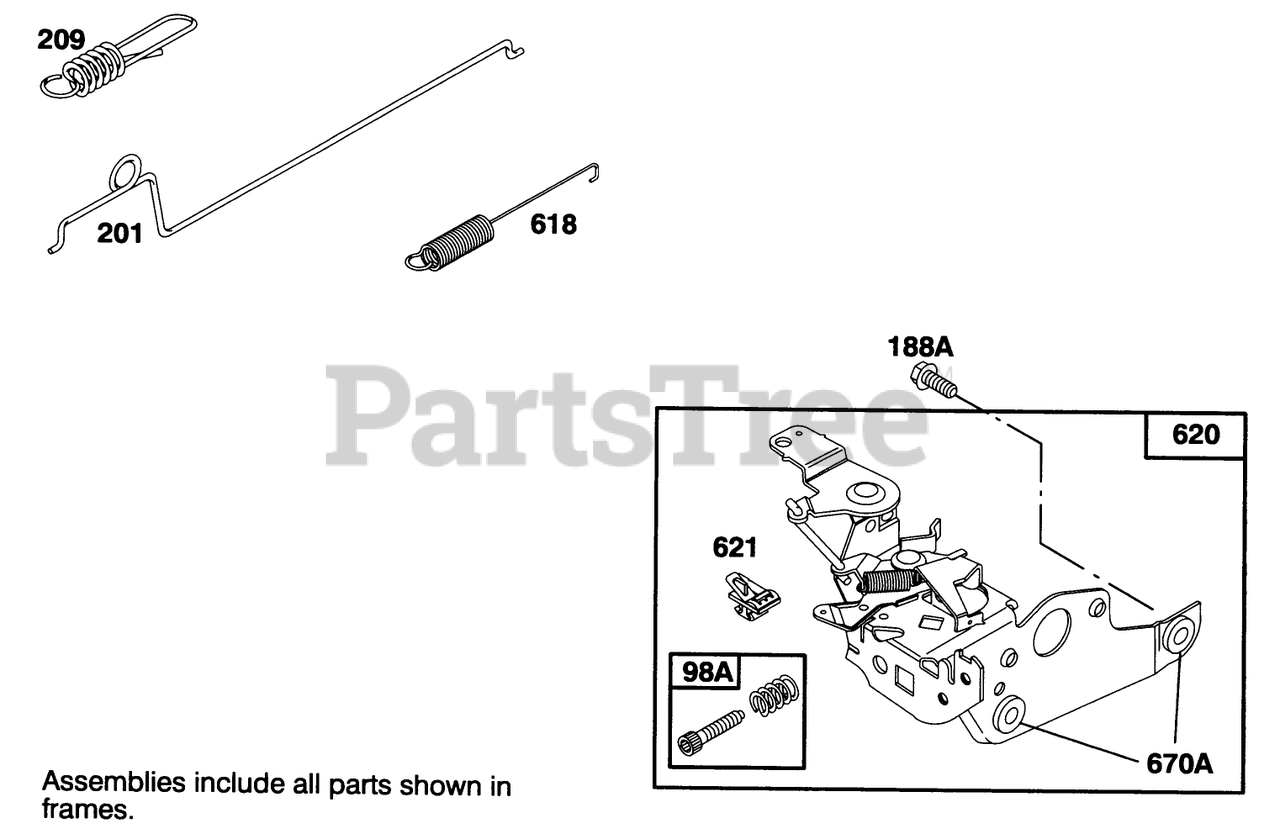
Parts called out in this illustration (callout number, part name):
98A	Screw Assy.
188A	Screw-Hex.
201	Link-Govemor
209	Spring-Govemor
618	Spring-Choke
620	Bracket-Control
621	Switch
670A	Spacer
